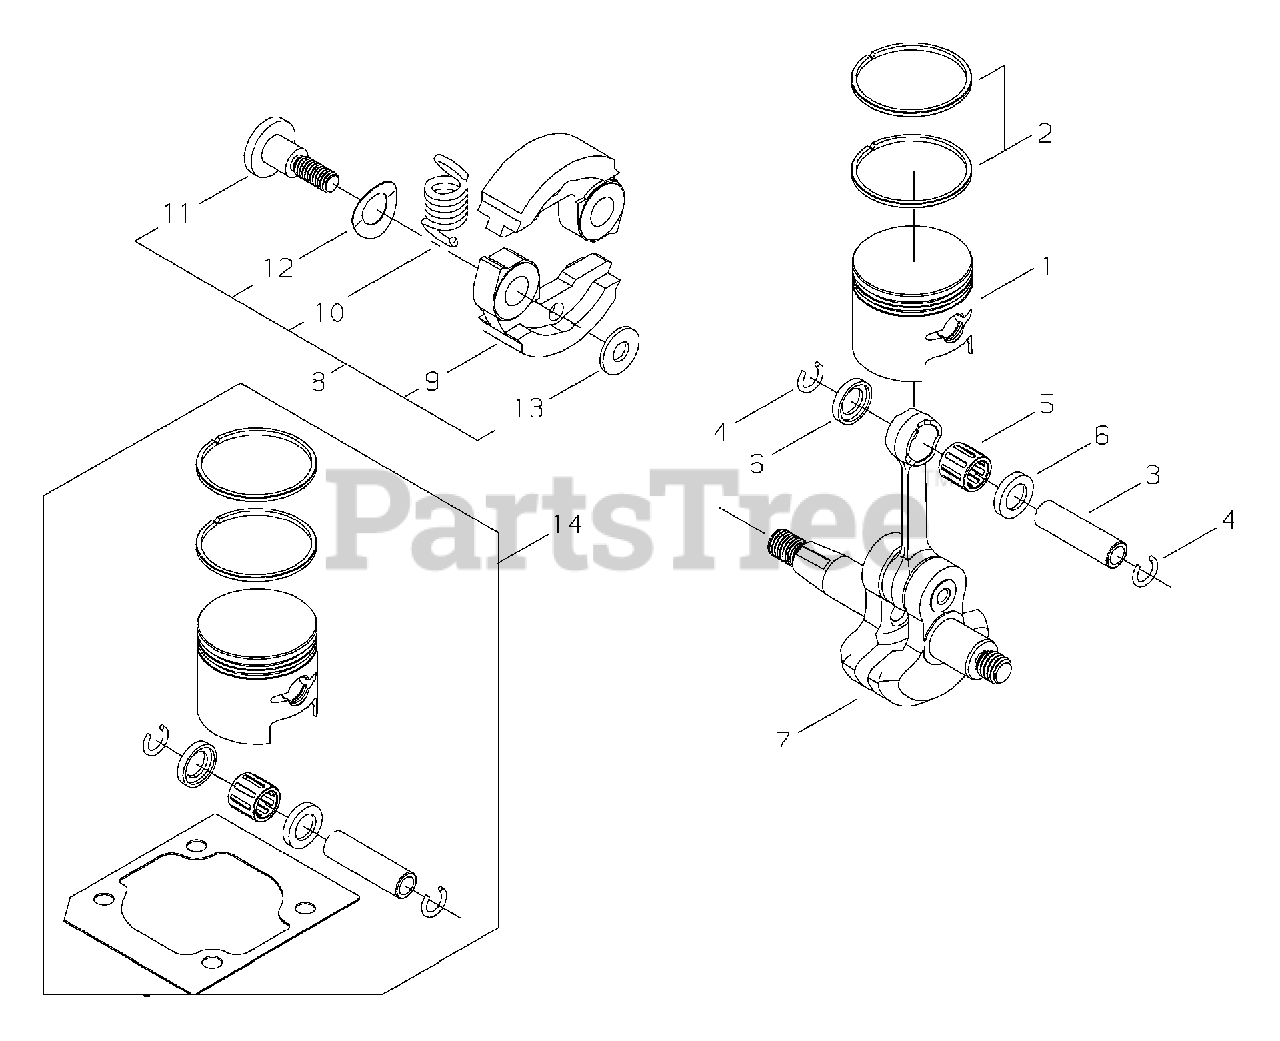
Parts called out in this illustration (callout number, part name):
1	PISTON
2	RING, PISTON
3	PIN, PISTON
4	RING, RETAINING
5	BEARING, NEEDLE - 8
6	SPACER, PISTON
7	CRANKSHAFT ASSY
8	CLUTCH ASSY
9	SHOE, CLUTCH
10	SPRING, CLUTCH
11	BOLT, CLUTCH
12	WASHER - SPRING
13	WASHER - 6
14	PISTON KIT
